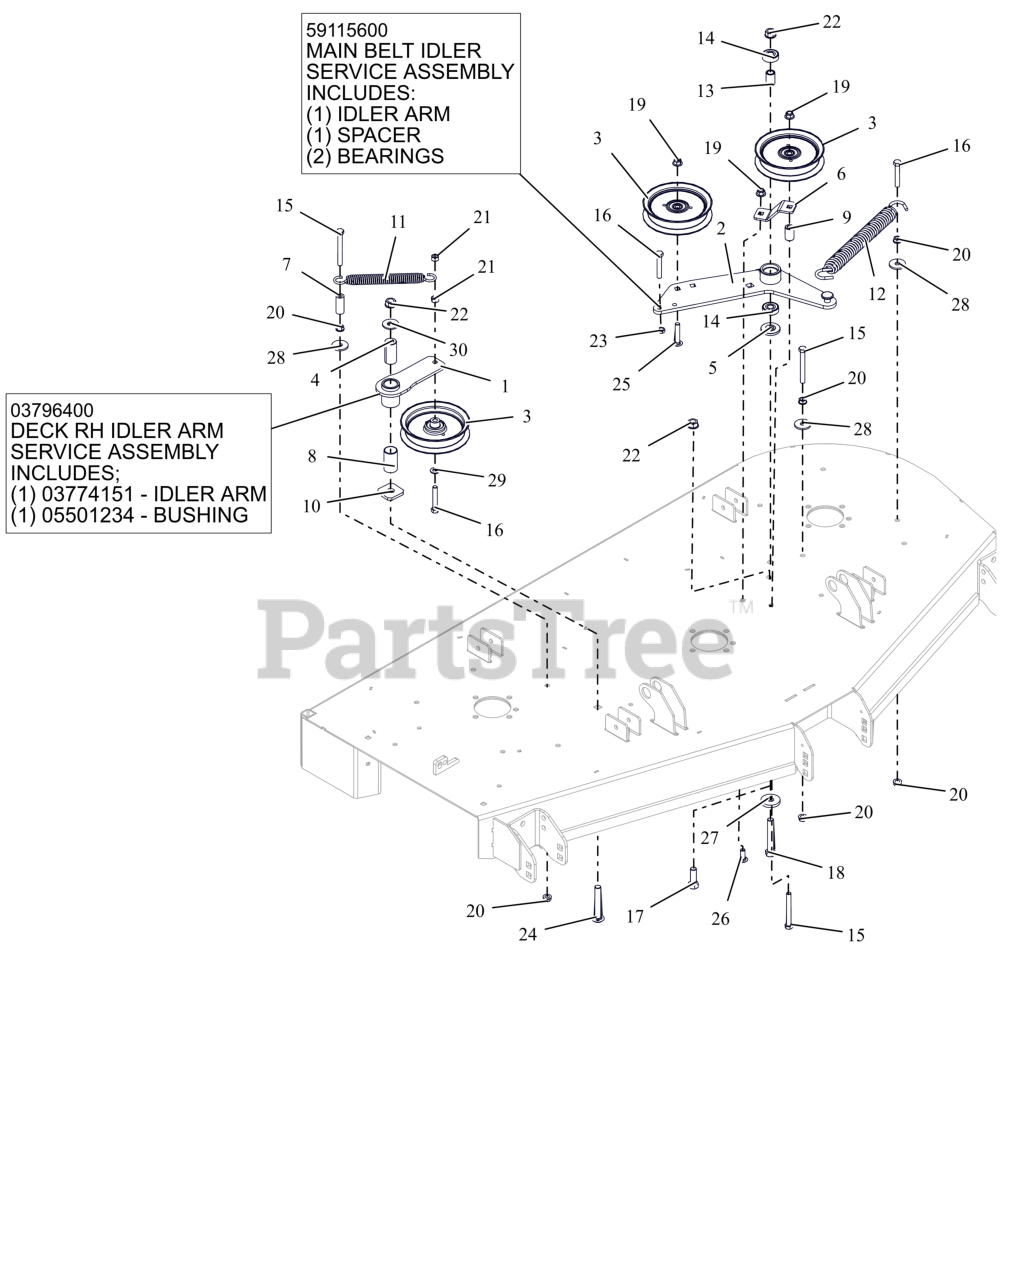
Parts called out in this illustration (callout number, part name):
1	WMT, IDLER ARM - BLACK
1	ASM, IDLER ARM (DECK)
2	WLDMT, DECK PTO IDLR ARM
2	ASSEMBLY, MAIN BELT IDLER
3	IDLER, FLAT 5.00"
4	BSHG, SPCR .502X.997X2.03 PM
5	SPACER, IDLER ARM
6	PTO FIXED IDLER MTG BRKT -RED
7	HOSE, .38 X 1.65
8	BSHG, 1.00X1.125X1.937
9	BUSHING, SLV .380X.750X1.190
10	WSHR-FLT .640X1.75X.250
11	SPRING, EXTENSION
12	SPRING, EXTENSION
13	SPACER .510 X .75 X 1.1485
14	BRG-BALL .500X1.38X.437
15	BLT, HEX .38-16X3.25 G5 ZCC
16	BLT,HEX .38-16X2.25 G5 ZCC
17	BLT,HEX .50-13X1.50 G5 ZCC
18	BLT,HEX .50-13X3.25 G5 ZCC
19	NUT,NYL-FLG .38-16 GF ZCC
20	NUT, SPNLK-FLG .38-16 G5 ZCC
21	NUT-LK-CTR .38-16 ZC120
22	NUT-LK-CTR-FLG .500-13 GG ZCC
23	NUT-JAM .375-16 G2 ZCC
24	BTL,RHSSN .500-13 X 3.25 G5 ZCC
25	BLT,RHSSN.375-16X2.00 G5 ZCC
26	BLT,RHSSN .38-16X1.00 G5 ZCC
27	WSHR-FL-STL 0.557X1.625X0.25 ZCC
28	WSHR,FLT .406X1.375X.135 ZCC
29	WSHR,FLT .406X.812X.065 ZCC
30	WSHR,FLT .563X1.375X.109 ZCC
